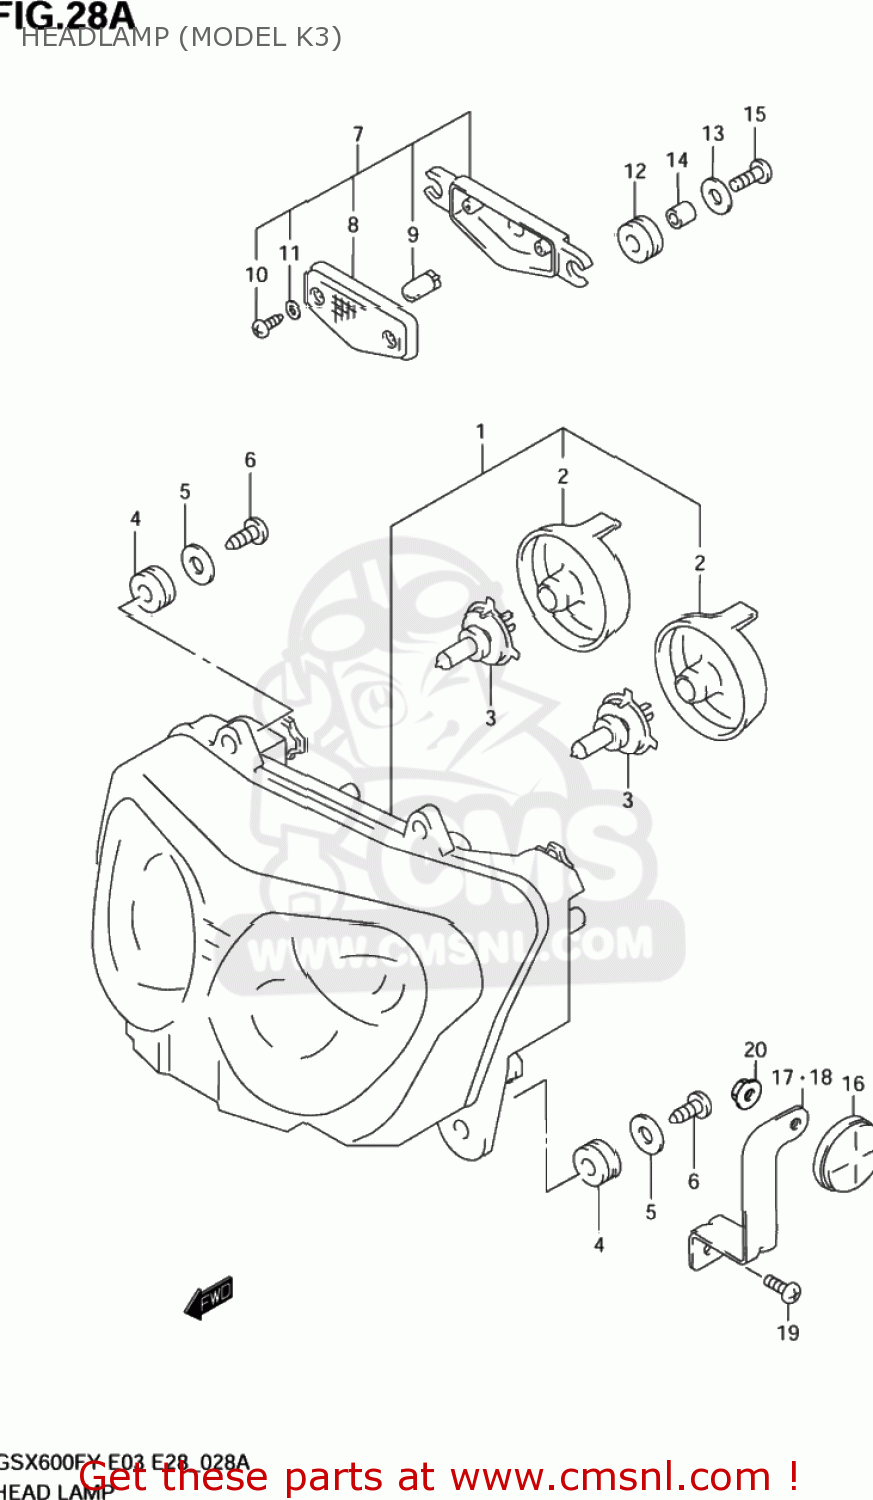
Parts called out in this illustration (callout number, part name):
1	HEADLAMP ASSY
2	COVER,SOCKET
3	BULB(12V60/55W,H4)
4	CUSHION,HEADLAMP
5	WASHER(5.5X18X1)
6	SCREW
7	LAMP ASSY,FR POSITION
8	LENS
9	BULB(12V5W)
10	SCREW
11	WASHER
12	CUSHION
13	WASHER(5.5X18X1)
14	SPACER(5.5X8X10.5)
15	SCREW 5X20
16	REFLECTOR,REFLEX FR
17	BRACKET,FR SIDE
18	BRACKET,FR SIDE RR,L
19	SCREW
20	NUT
